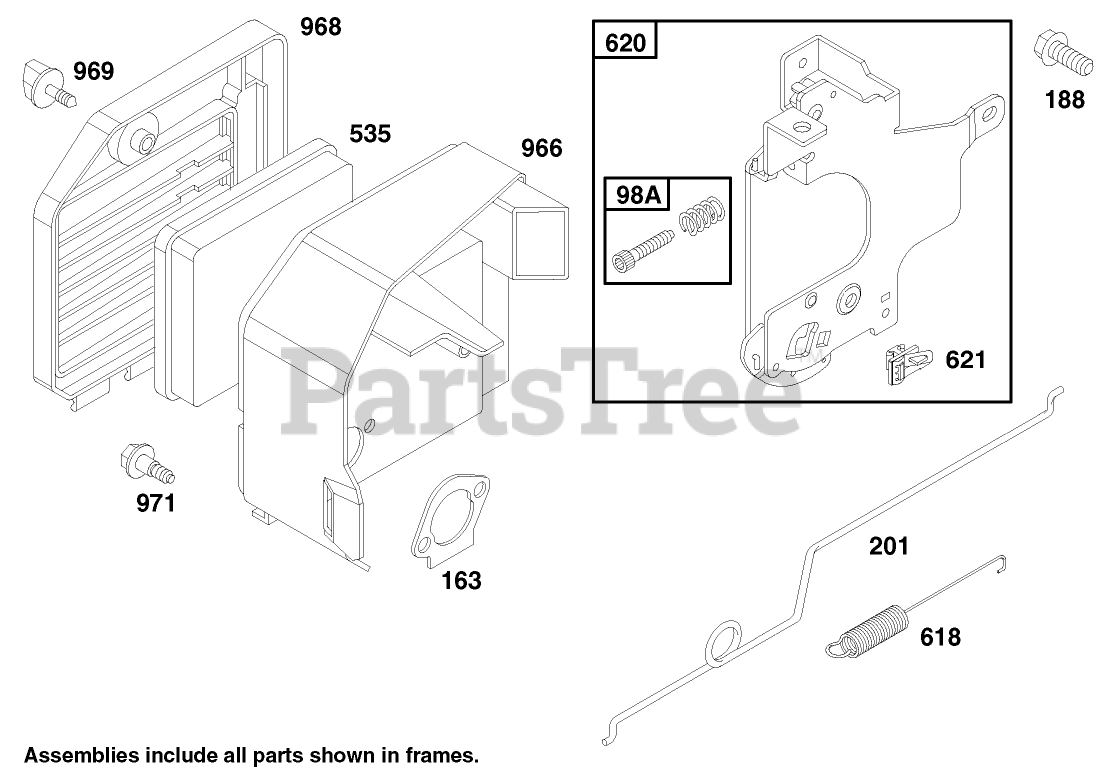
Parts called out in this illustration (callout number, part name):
98A	SPEED ADJUST. SCREW ASM
163	AIR CLEANER GASKET
188	SCREW - HEX HEAD
201	GOVERNOR LINK
535	FILTER ELEMENT
618	RETURN SPRING
621	STOP SWITCH
966	AIR CLEANER BASE
969	AIR CLEANER SCREW
971	AIR CLEANER SCREW
